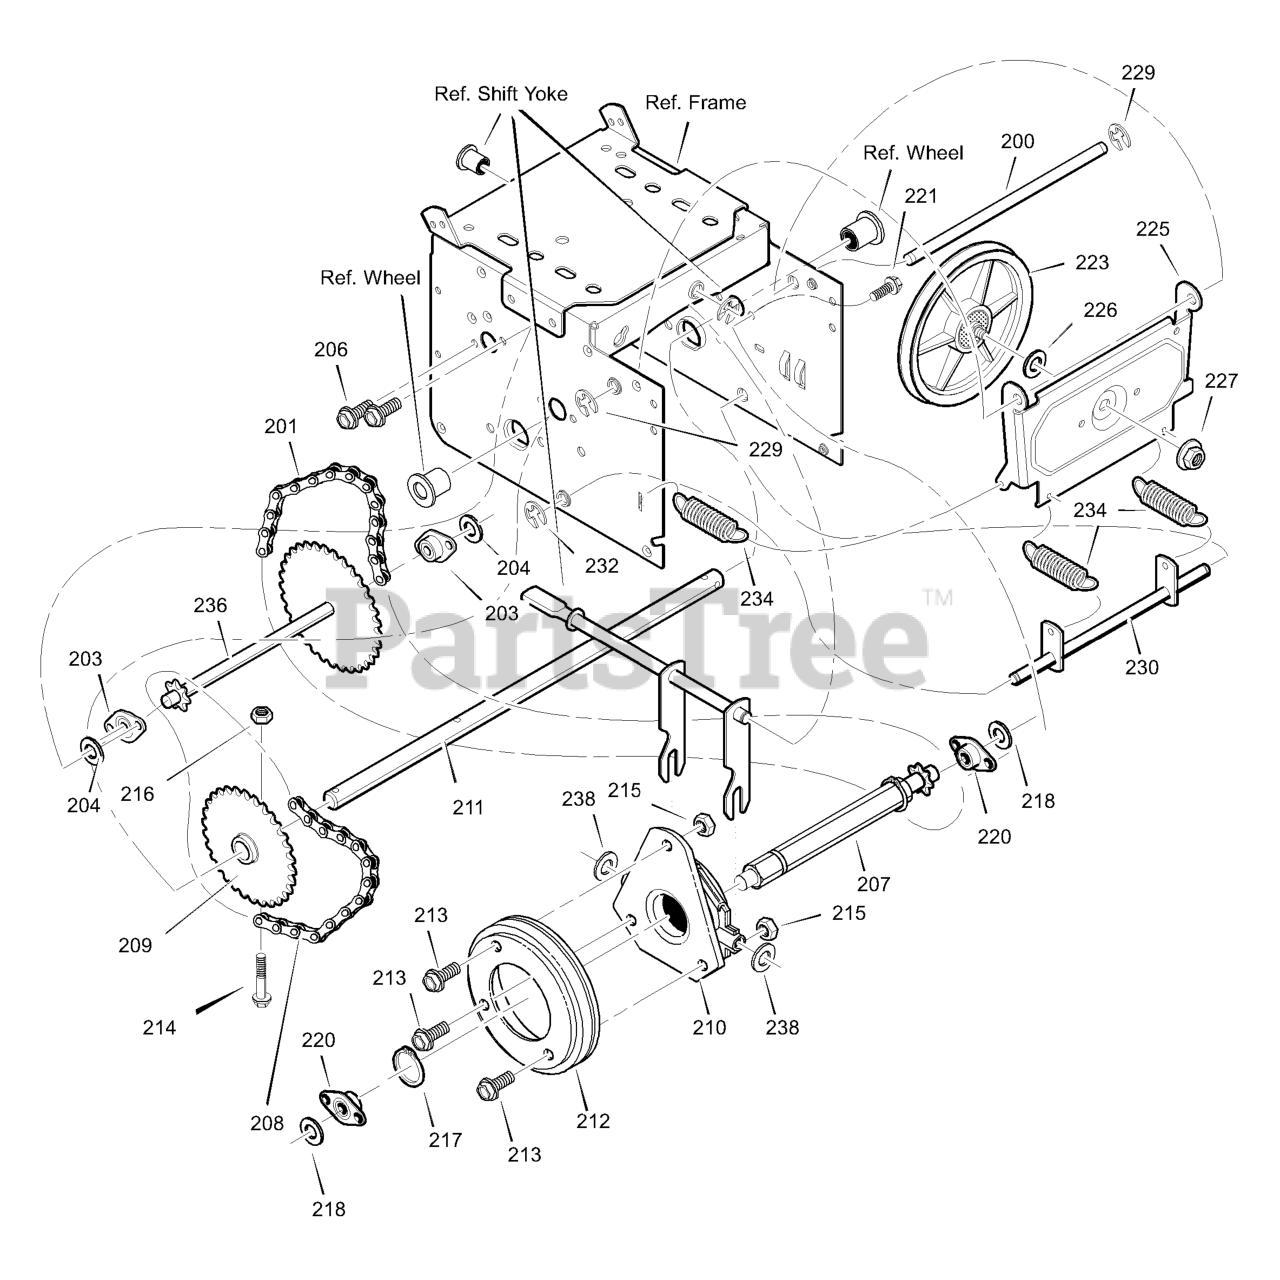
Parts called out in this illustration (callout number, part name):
200	LF AXLE, SWING PLATE YZ
201	CHAIN, ROLLER #420 x 19.00 LG
203	BEARING AND RETAINER, ASSY
204	BEARING
206	SCREW, TAP 5/16-18 x 0.5
207	ASSY, HEX SHAFT
208	CHAIN, ROLLER #420 x 18.00 LG
209	SPROCKET ASSEMBLY
210	BEARING, TRUNION CLUTCH R
211	AXLE - BEARING ASSEMBLY
212	WHEEL, FRICTION DISC
213	SCREW, 1/4-20 x 0.63
214	BOLT, 1/4-20 x 1.75
215	NUT, KEPS HEX 1/4-20
216	NUT, 1/4-20 HEX NYLOCK
217	RING, RETEXT
218	BRARING
220	BEARING AND RETAINER, ASSY
221	SCREW, TAP 5/16-18 X .50
223	ASSY, FRICTION PULLEY
225	LF PLATE, SWINGING YZ
226	SPACER, FRICTION PULLEY
227	NUT, FLANGE LOCK 3/8-24
229	RETAINER, RING
230	LF ASSY, SPRING LINK YZ
232	RETAINER, RING
234	SPRING, EXTENSION
236	WLD, INTERMED SPROCKET 33T/7
238	WASHER, FLAT
